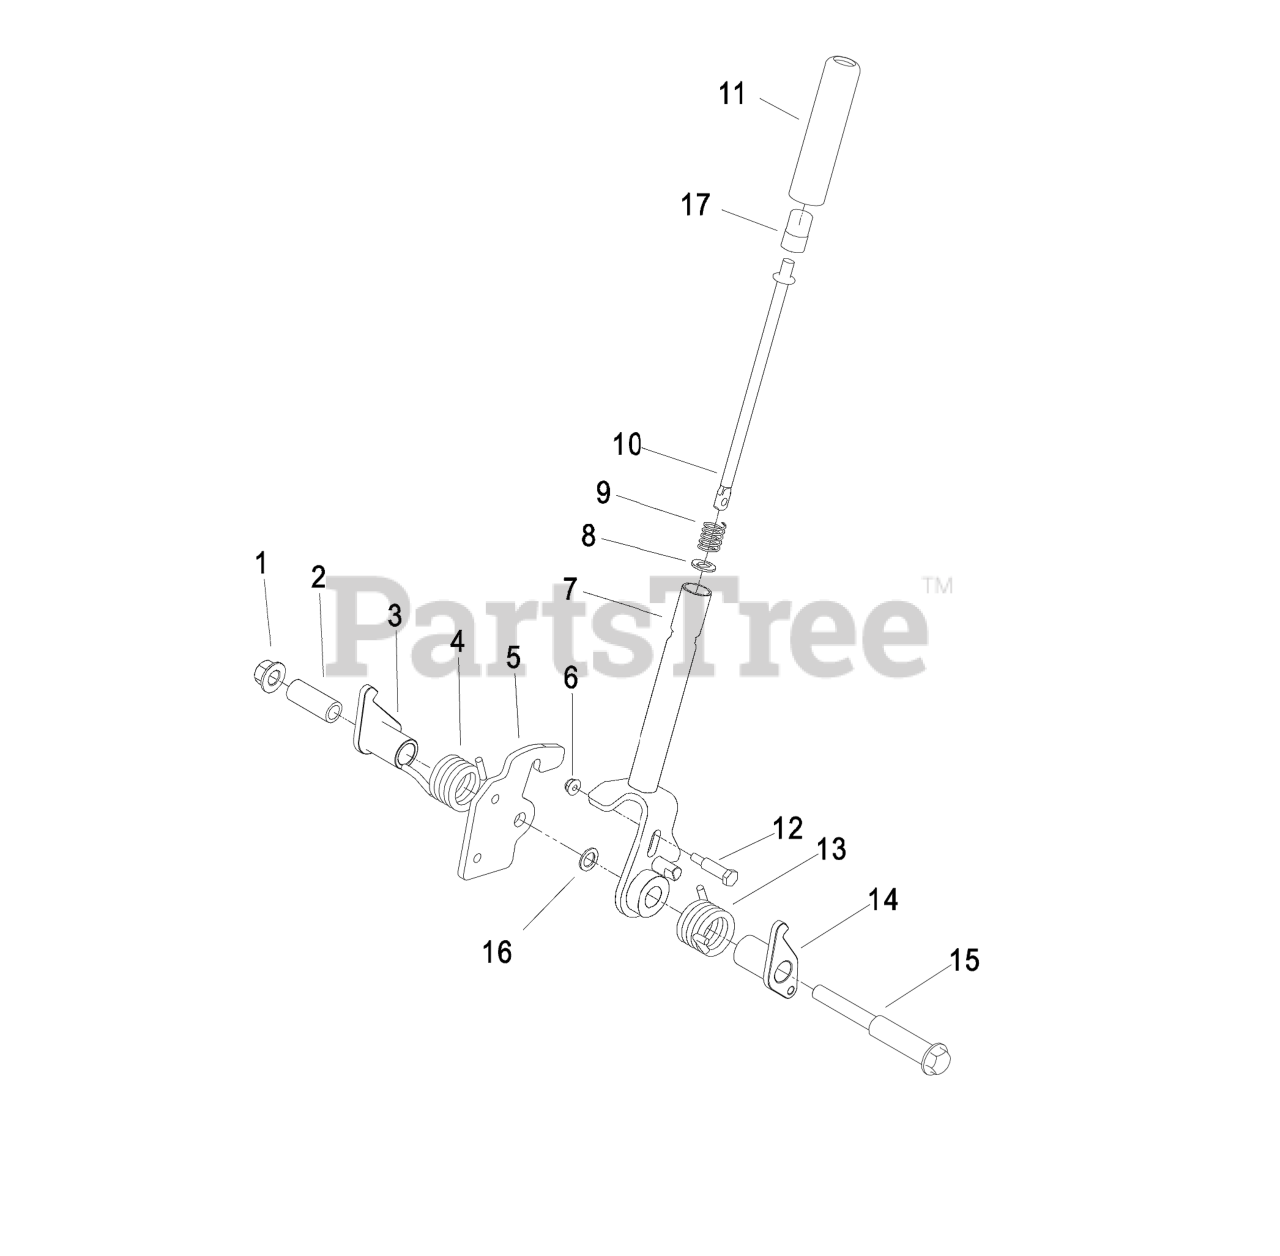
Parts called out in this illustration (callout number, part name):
1	Nut-Lock 1/2-13
3	ARM-BRAKE, LH
4	SPRING-TORSION, RH
5	PLATE-LATCH
8	WASHER-SPECIAL
9	SPRING-COMPRESSION
10	ROD-RELEASE, BRAKE
12	BOLT-SHOULDER
13	SPRING-TORSION, LH
14	ARM-BRAKE, RH
15	BOLT-SHOULDER
